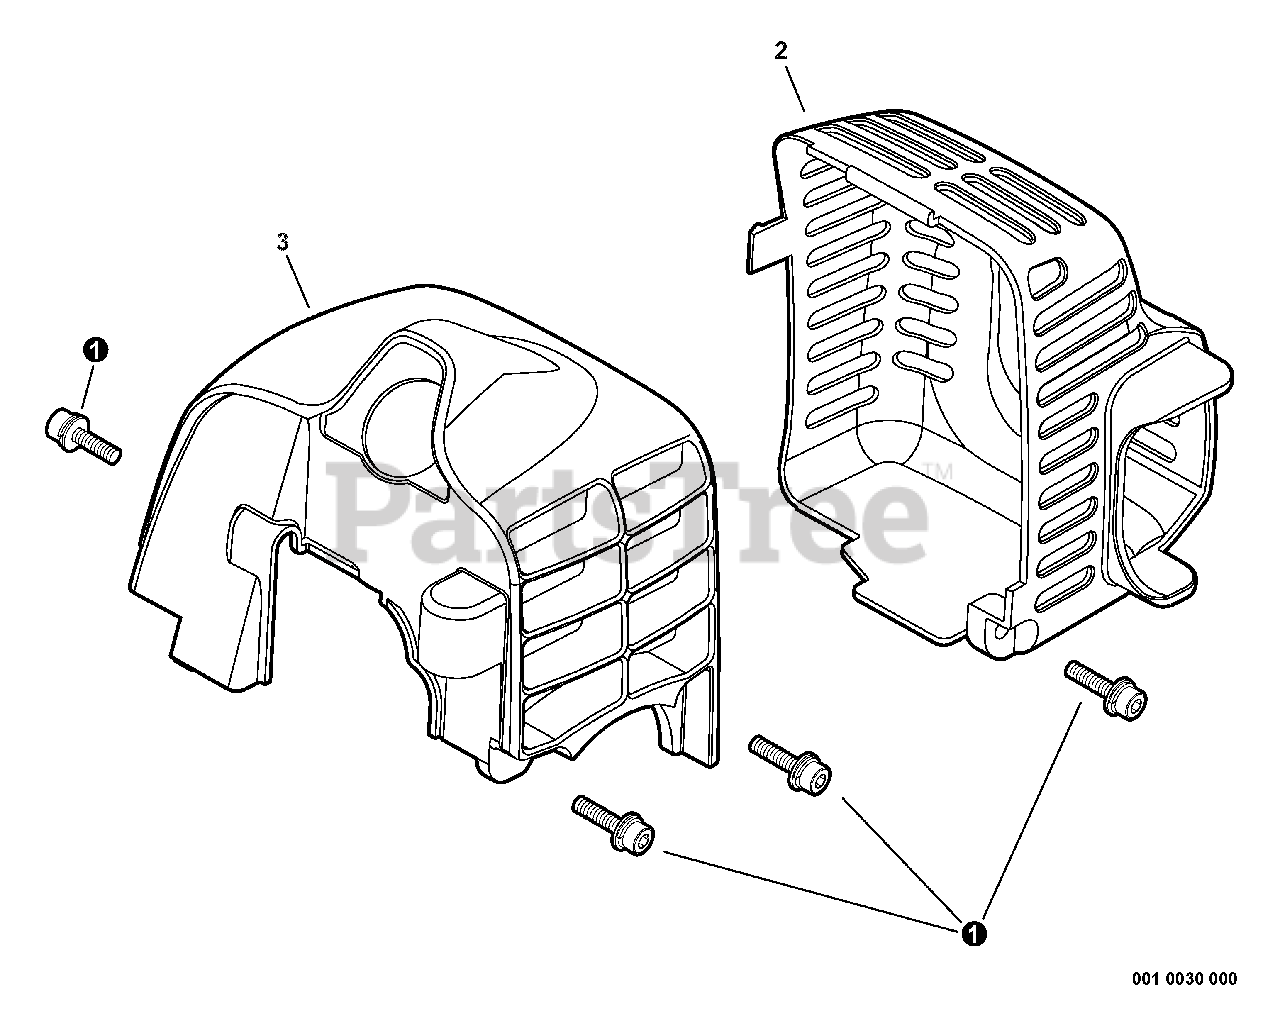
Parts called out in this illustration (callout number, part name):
1	SCREW - 5X20
2	COVER, EXHAUST
3	COVER, ENGINE
